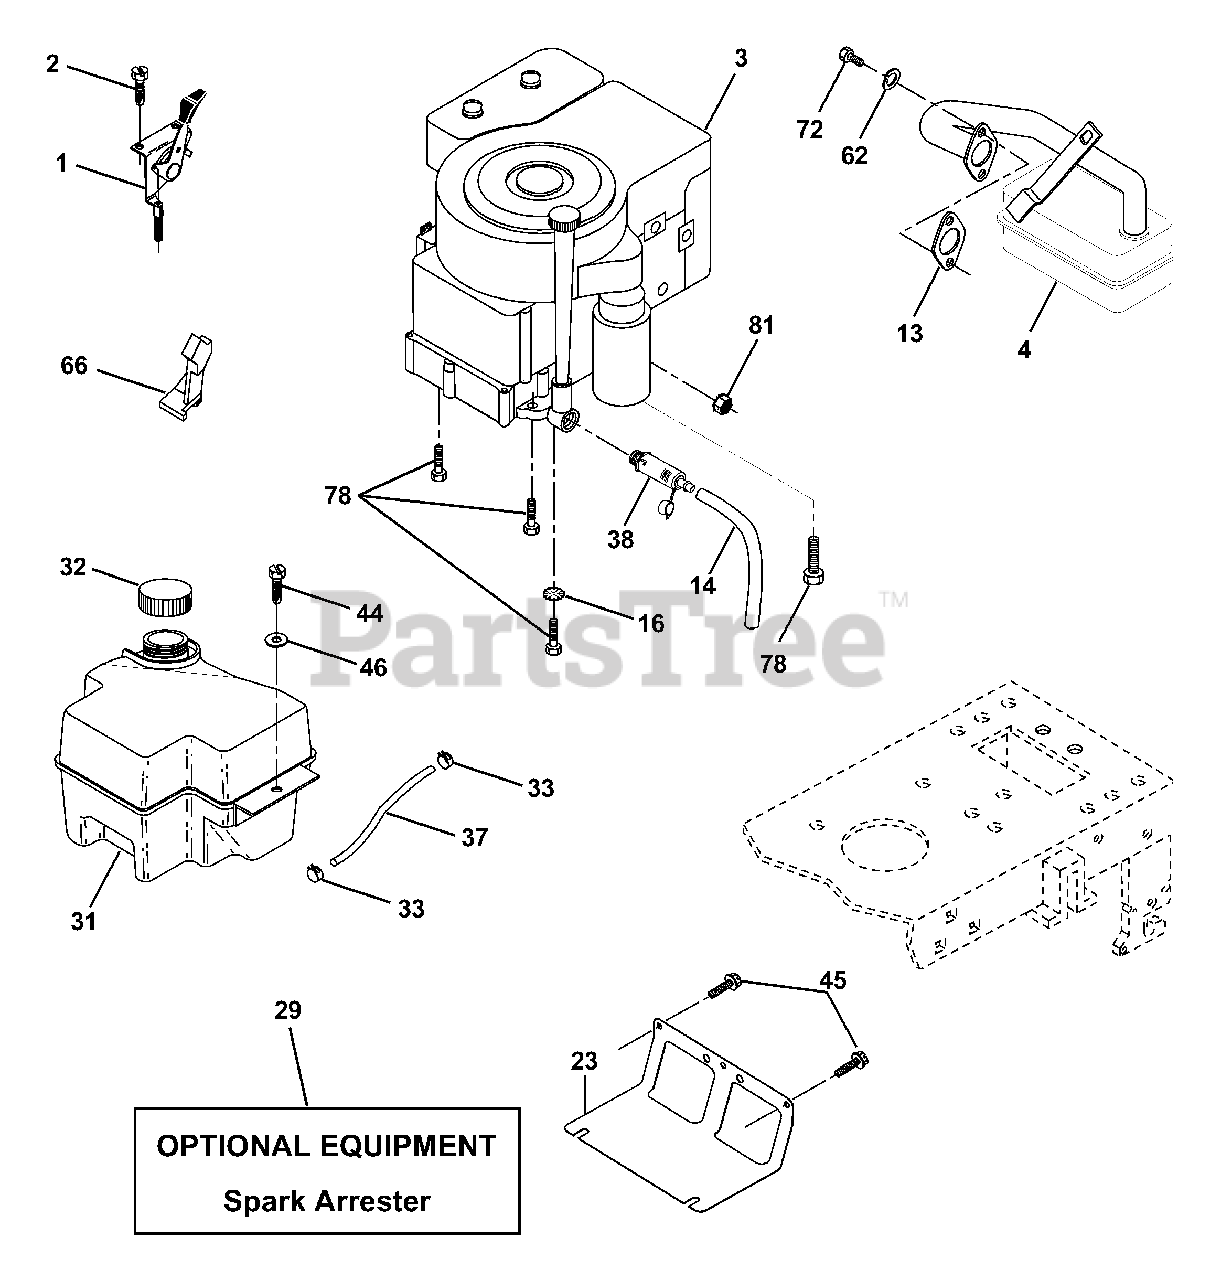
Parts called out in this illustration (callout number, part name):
1	Control Th/ch Flag
2	Screw Hex Thd Cut 1/4-20x5/8 T
4	Muffler LT B&S 12/12.5/13HP
13	Gasket Eng 1 313 Id Tin Plated
14	Tube Drain Oil Easy
16	Washer Lock Ext Tooth 3/8
23	Shield Browning/Debris Guard
29	Kit Spark Arrestor (Flat Scrn)
31	Tank Fuel Front 2 00
32	Cap Asm Fuel W/sym Vented
33	Clamp Hose Black
37	Line Fuel 20"
38	Plug Drain Oil Easy
44	Screw Hexwsh Thdrol 1/4-20x3/4
45	Screw Hex Wsh Thdr 3/8-16 x 3/4
46	Washer 9/32 X 7/8 X 16 Ga
62	Washer Lock Hvy Hlcl Spr 5/16
66	Stop Throttle 3000 RPM
72	Screw Hexhd Cap 5/16-18x 3/4
78	Screw 3/8-16x1-1/4 Smgml Tap/R
81	Nut Keps Hex 1/4-20 Starter Nut
